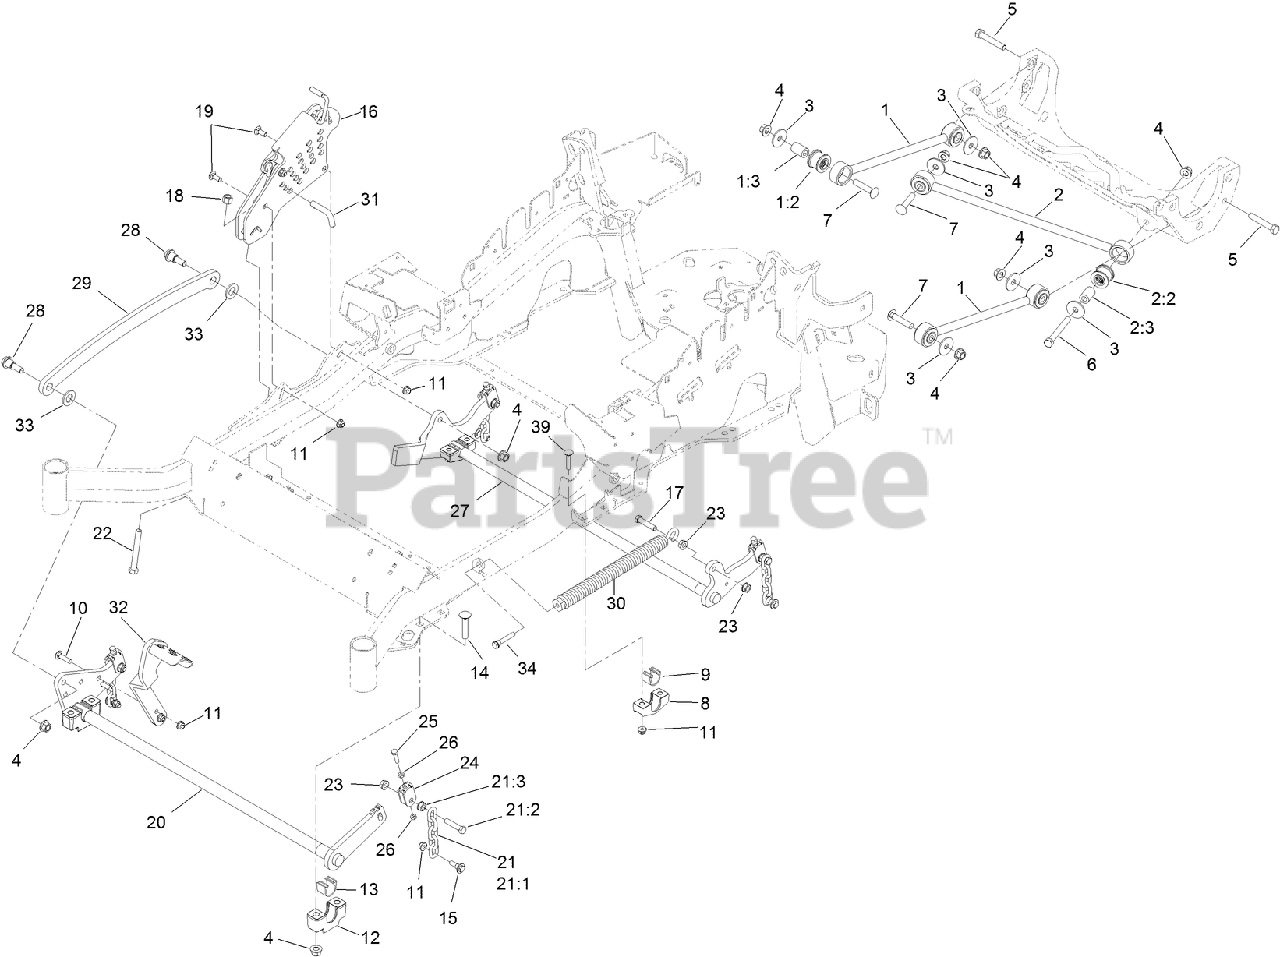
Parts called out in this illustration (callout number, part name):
1	DECK STRUT ASM
1:2	BUSHING-SUSPENSION, RUBBER
1:3	SPACER
2	PANHARD ROD ASM
2:2	BUSHING-SUSPENSION, RUBBER
2:3	SPACER
3	WASHER-THRUST
4	NUT-LOCK
5	SCREW-HH
6	SCREW-HH
7	SCREW-CARR
8	SUPPORT-CROSS SHAFT, REAR BEARING
9	BEARING-CROSS SHAFT, REAR
10	SCREW-CARR
11	NUT-HF, NI
12	SUPPORT-CROSS SHAFT, BEARING
13	BEARING-CROSS SHAFT, FRONT
14	BOLT-CARR
15	SCREW-SHOULDER, HHF
16	HOC ASM
17	SCREW-HH
18	NUT-LOCK, NI
19	BOLT-CARR
20	CROSS SHAFT-FRONT
21	DECK LIFT CHAIN ASM
21:1	CHAIN-LIFT, DECK
21:2	SCREW-HH
21:3	NUT-HF
22	BOLT-TAP
23	NUT-HF
24	YOKE-ADJUST, DECK
25	SCREW-HH
26	NUT-JAM
27	LIFT-DECK, REAR
28	SCREW-SHOULDER, HHF
29	LINK-LIFT, DECK
30	SPRING-EXTENSION
31	PIN-HOC
32	LEVER-FOOT
33	WASHER-FLAT
34	BOLT-SHOULDER
39	SCREW-CARR
